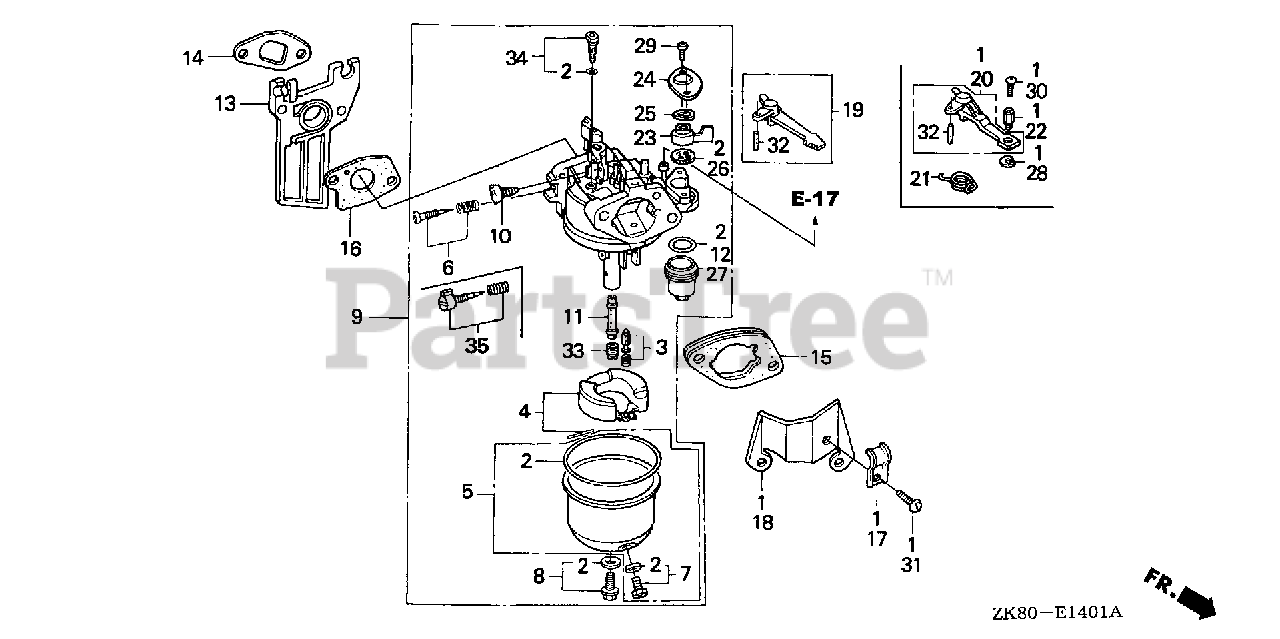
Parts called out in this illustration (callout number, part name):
1	CHOKE KIT, REMOTE CONTROL
2	GASKET SET
3	VALVE SET, FLOAT (SEAT NOT INCLUDED)
4	FLOAT SET
5	CHAMBER SET, FLOAT
6	SCREW SET, PILOT (CARBURETOR NO.)
7	SCREW SET, DRAIN
8	SCREW SET
9	CARBURETOR ASSY. (BE11C B)
9	CARBURETOR ASSY. (BE11C C)
10	SCREW, THROTTLE STOP
11	NOZZLE, MAIN
12	GASKET, FUEL STRAINER CUP
13	INSULATOR, CARBURETOR
14	GASKET, INSULATOR
15	SPACER, CARBURETOR
16	GASKET, CARBURETOR
17	HOLDER, CONTROL CABLE
18	STAY, CHOKE CONTROL
19	LEVER, CHOKE (STD)
20	LEVER, CHOKE (REMOTE)
21	SPRING, RETURN
22	HOLDER, CABLE
23	LEVER, PETCOCK
24	PLATE, LEVER SETTING
25	SPRING, PETCOCK LEVER
26	GASKET, PETCOCK
27	CUP, FUEL STRAINER
28	CIRCLIP (5MM)
29	SCREW, PAN (3X6)
30	SCREW, PAN (4X8)
31	SCREW, PAN (5X8)
32	PIN, SPRING (2X12)
33	JET, MAIN (#65)
33	JET, MAIN (#68)
33	JET, MAIN (#62)
34	JET SET, PILOT (#38)
